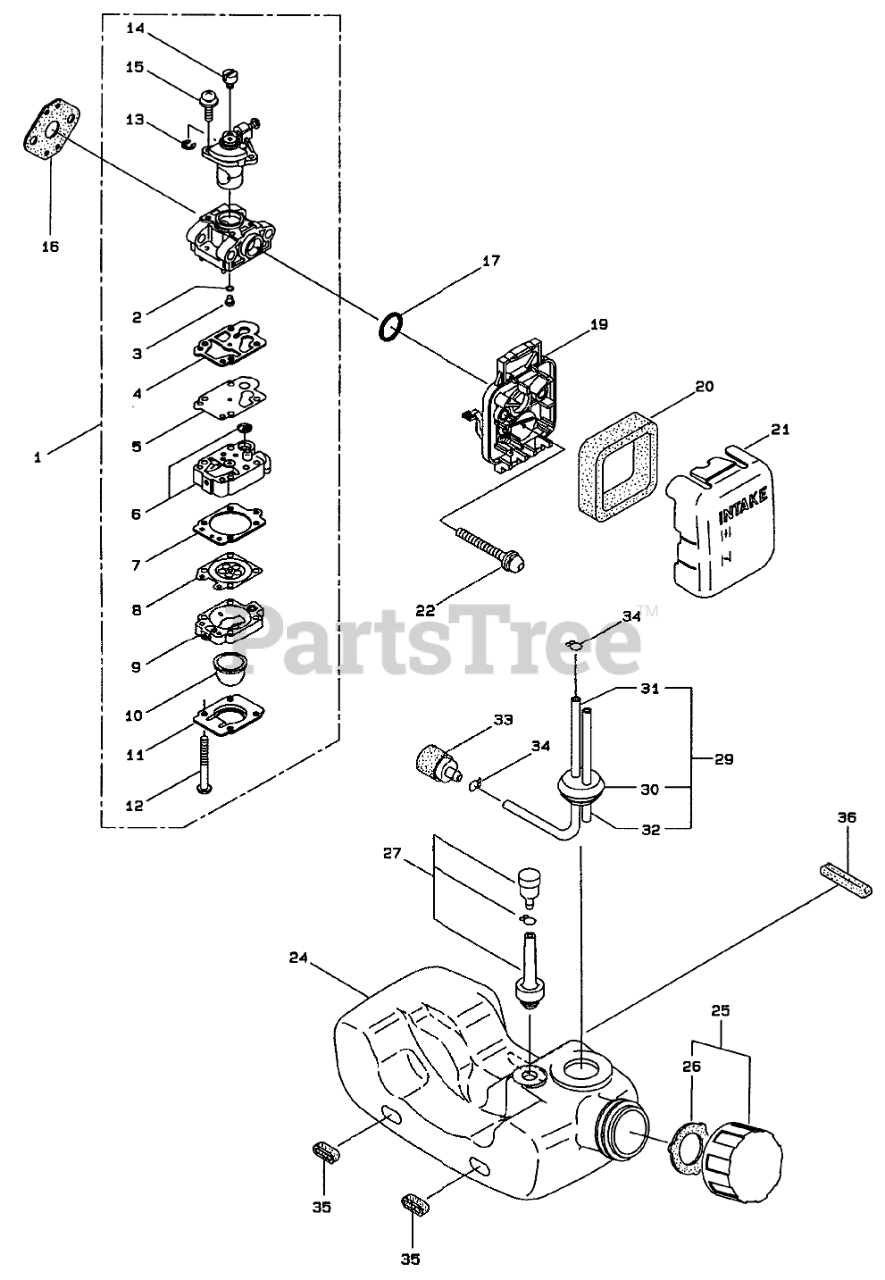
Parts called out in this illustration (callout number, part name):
1	Carburetor Assembly (Incl. Ref. #2-15)
2	O-RING
3	Main Jet
4	GASKET (NC)
5	PUMP - DIAPHRAGM (NC)
6	PUMP - BODY (NC)
7	GASKET (NC)
8	ASM - DIAPHRAGM
9	PURGE - BODY (NC)
10	PRIMER
11	PLATE - COVER (NC)
12	SCREW (NC)
13	E-RING
14	SWIVEL
15	SCREW
16	GASKET
17	O-RING
19	HOUSING - AIR CLEANER
20	ELEMENT
21	COVER
22	CAPSCREW
24	GAS TANK
25	Fuel Tank Cap Assembly (Incl. Ref. # 26)
26	PACKING
27	ASM - BREATHER
29	Fuel Pipe Assembly (Incl. Ref. # 30-32)
30	GROMMET
31	Fuel Pipe
32	PIPE - RETURN
33	GAS FILTER
